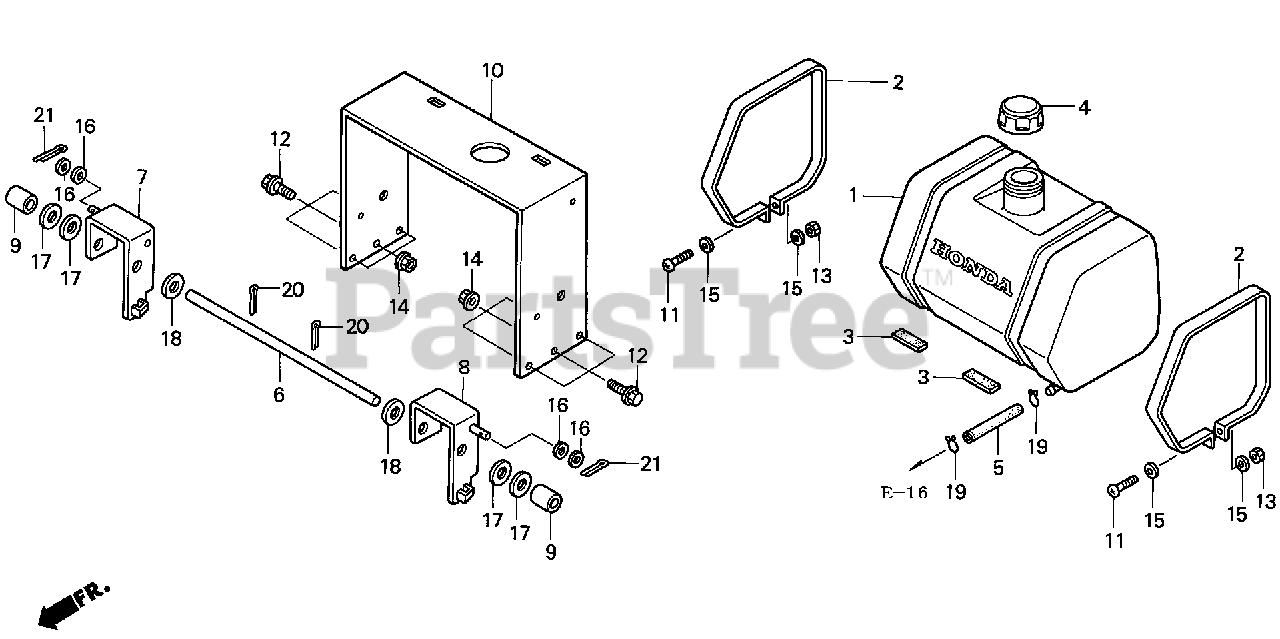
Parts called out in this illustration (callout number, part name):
1	TANK, FUEL
2	STRAP, FUEL TANK
3	PAD, FUEL TANK
4	CAP ASSY., FUEL TANK
5	TUBE, FUEL
6	SHAFT, CLUTCH LINK
7	ARM, R. CLUTCH
8	ARM, L. CLUTCH
10	SUPPORT, HANDLE
11	SCREW, PAN (10-24X1 3/4") (NOT AVAILABLE)
12	BOLT, WHIZ-LOCK (1/2-13X1")
13	NUT (10-24)
14	NUT, WHIZ-LOCK (1/2"-13)
15	WASHER, FLAT (#10)
16	WASHER, FLAT (3/8")
17	WASHER (3/4"-1 1/4"X18)
18	WASHER, FLAT (3/4")
19	CLAMP, FUEL
20	PIN, COTTER (1/8X1 1/2")
21	PIN, COTTER (1/8X3/4")
